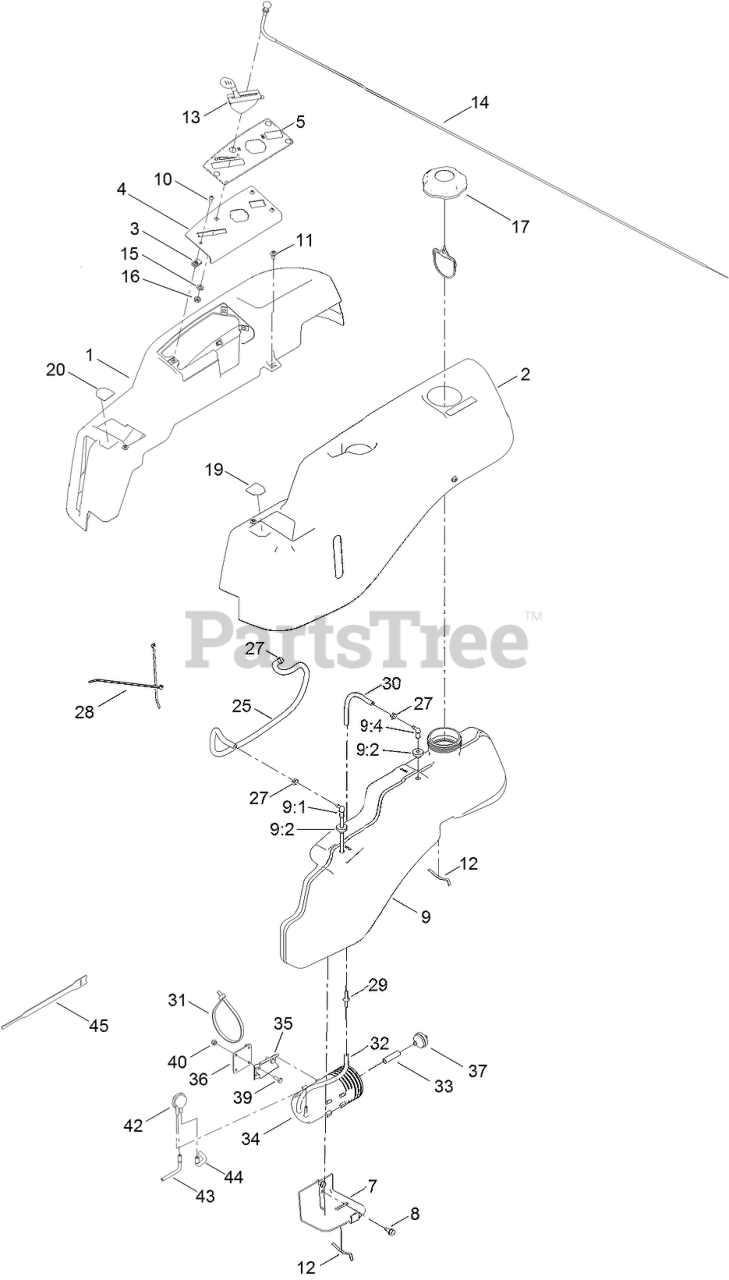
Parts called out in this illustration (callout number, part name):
1	POD-RH
2	POD-LH
4	PLATE-CONTROL
5	DECAL-PANEL, CONTROL
7	SUPPORT-TANK, FRONT
8	SCREW-HWHTF
9	FUEL TANK ASM
9:1	CONNECTOR-ELBOW, 90 DEG
9:2	BUSHING
9:4	FITTING-PLASTIC
10	SCREW-PRH
11	SCREW-SHOULDER
12	SPRING
13	CABLE-THROTTLE
14	CABLE-CHOKE
15	WASHER-LOCK
16	NUT-HJ
17	CAP-FUEL, RATCHETING
19	DECAL-LEVER, CONTROL (LH)
20	DECAL-LEVER, CONTROL (RH)
25	HOSE-FUEL
27	CLAMP-HOSE
28	TIE-CABLE
29	ADAPTOR-ORIFICE
30	HOSE-FUEL
31	TIE-CABLE
32	HOSE-FUEL
33	HOSE-FUEL
34	CANISTER-CARBON, 800CC
35	BRACKET-CANISTER, CARBON
36	PLATE-ADAPTER
37	FILTER-FUEL, INLINE
39	SCREW-HH
40	NUT-LOCK, NI
42	VALVE-CONTROL, VACUUM
43	HOSE-VENT, FORMED
44	HOSE-VENT, FORMED
45	STRAP-VELCRO, CABLE TIE
